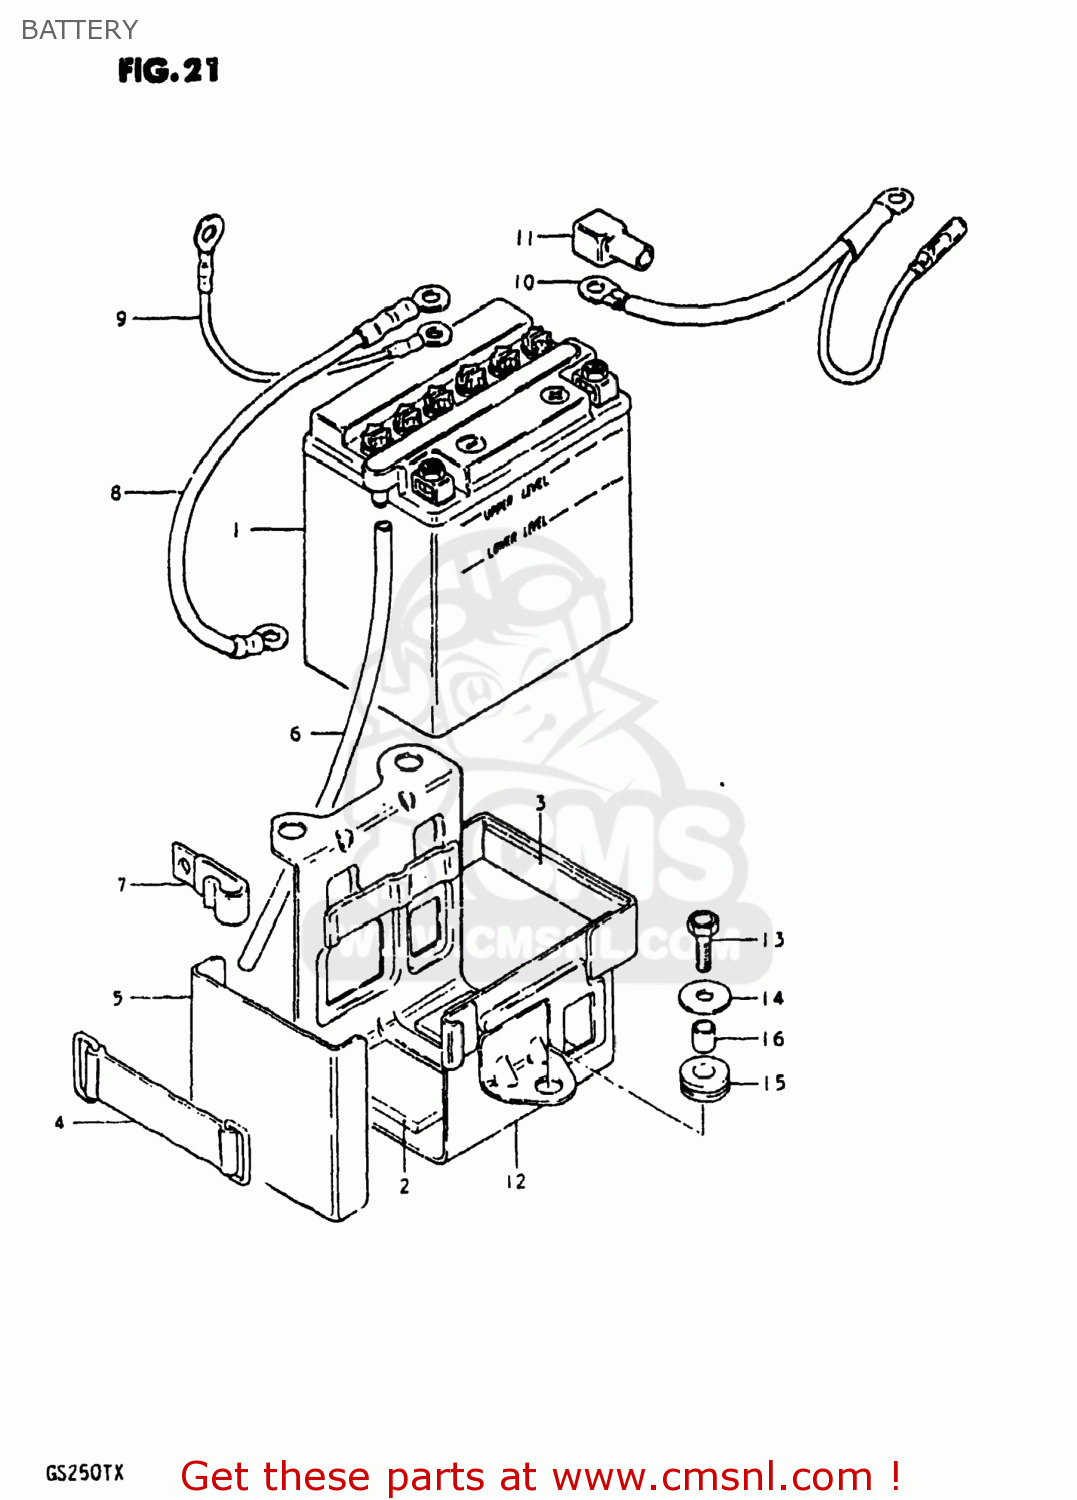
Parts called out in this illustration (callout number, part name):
1	BATTERY ASSY (12V)
2	CUSHION,BATTERY
3	PROTECTOR,20X9
4	BAND
5	COVER,BATTERY
6	HOSE,BATTERY EXHAUST
7	CLAMP
8	CORD,BATTERY MINUS
9	WIRE
10	WIRE,BATTERY PLUS
11	CAP,TERMINAL
12	HOLDER,BATTERY
13	BOLT
14	WASHER
15	CUSHION
16	SPACER (6.1X9X9)
